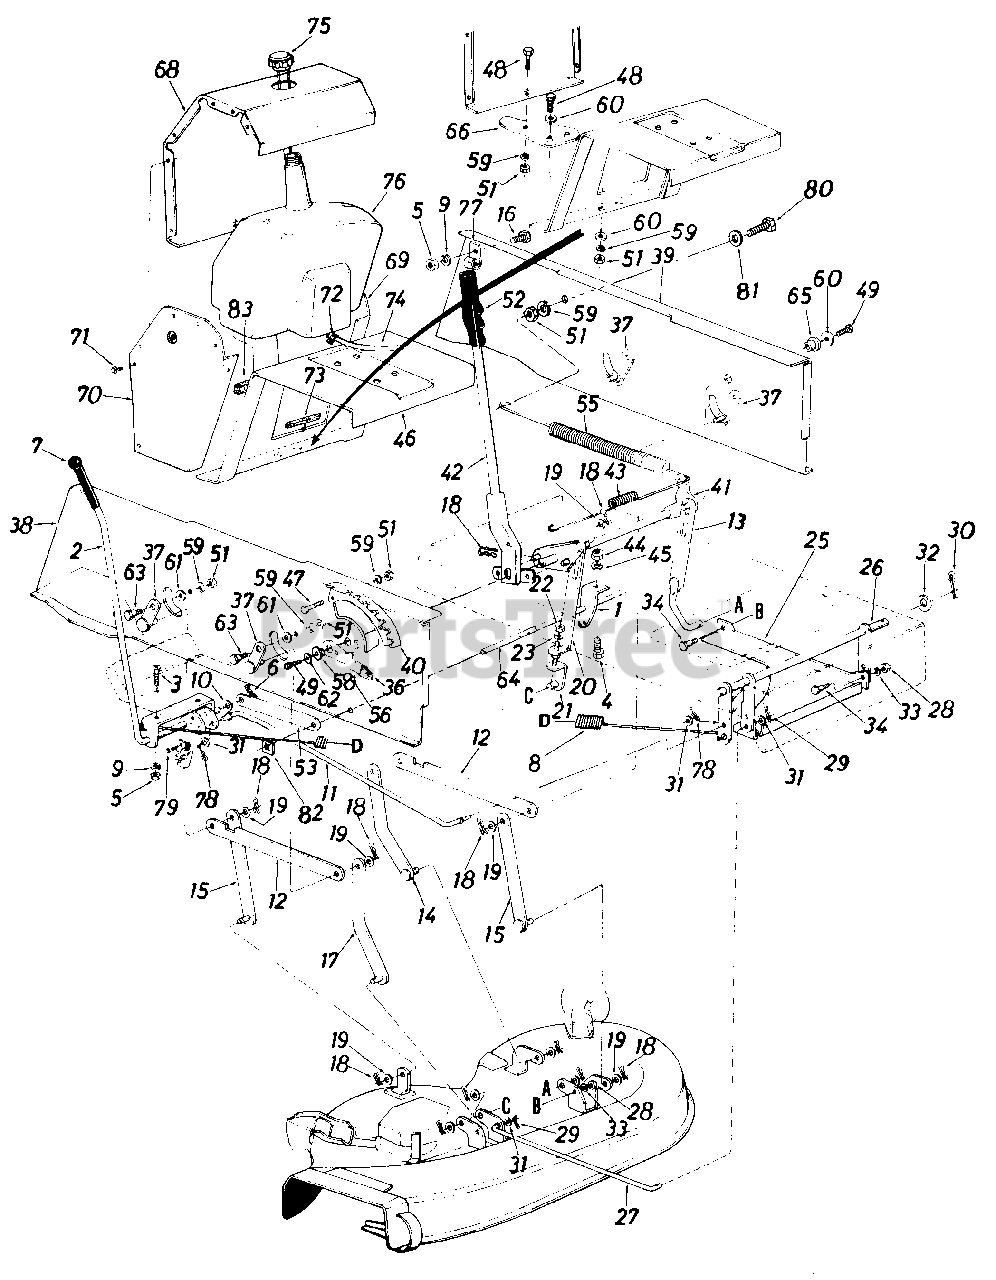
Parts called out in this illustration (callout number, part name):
1	Spring Hanger Bracket
2	Deck Engagement Lever Ass'y.
3	Truss Mach. Scr. 5/16-18 x .75" Lg.
4	Hex Bolt 1/4-20 x .62" Lg.
5	Hex Nut 5/16-18 Thd.
6	Cotter Pin 3/32" Dia. x 1.00" Lg.
8	Ext. Spring .99" O.D. x 22"
9	L-Wash 5/16 I.D.
10	Fl-Wash .510" I.D. x 1.0" 0. D.
11	Drive Deck Control Rod
12	Connecting Rod 3/16 x 1 x 12.5
13	Deck Lift Link Ass'y.
14	Deck Hanger Link Ass'y. Rear L.H.
15	Deck Hanger Link Ass'y.
16	Hex Bolt 5/16-18 x .75" Lg.
17	Deck Hanger Link Ass'y. Front R.H.
18	Inter. Cotter Pin 1/2" Dia.
19	Fl-Wash. .531 I.D. x .93" O.D.
20	Adj. Link Deck Lifting
21	Adj. Lower Link Ass'y.
22	Hex Jam Nut 3/8-24 Thd.
23	L-Wash. 3/8" I.D.
25	Diagonal Brace
26	Stabilizer Shaft Ass'y.
27	Stabiiizer Rod
28	Hex Nut 3/8-16 Thd.
29	Cotter Pin 3/32" Dia. x 1.0" Lg.
30	Cotter Pin 1/8" Dia. x 1.25" Lg.
31	Fl-Wash. .385" I.D. x .620" O.D.
32	Fl-Wash. .635" I.D. x 1.12" O.D.
33	L-Wash. 3/8" I.D.
34	Shoulder Bolt 3/8-16
36	Knob Height Adj.
37	Pivot Link Ass'y.
38	Side Panel Upper Frame R.H.
39	Side Panel Upper Frame L.H.
40	Index Brkt.
41	Lift Shaft Ass'y.
42	Lift Handle Brkt. Ass'y.
43	Ext. Spring .56" I.D. x 32 Coils
44	Hex Nut 1/4-20 Thd.
45	L-Wash. 1/4" I.D.
46	Hitch Plate
47	Hex Bolt 5/16-18 x .75" Lg.
48	Hex Bolt 5/16-18 x 1.00" Lg. (Grade 5)
49	Hex Wash. TT-Tap Scr. 5/16-18 x .62" Lg.
51	Hex Nut 5/16-18 Thd.
52	Grip
53	Link 1.0" x 7.5" x .19
55	Ext. Spring .99" Dia. x 11.00" Lg.
56	Deck Lift Down Stop
58	Flange Brg. .630" I.D.
59	L-Wash. 5/16" I.D.
60	Fl-Wash. .344" I.D. x 1.125" O.D. x .125
61	Fl-Wash. .344" I.D. x .62" O.D. x .063
62	Fl-Wash. .344" I.D. x 1.125" O.D.
63	Shld. Bolt .437" Dia. x .180
64	Running Board Rod
65	Flange Brg. .632" I.D.
66	Hitch Bar
68	Gas Tank Housing Main Panel
69	Side Panel L.H. Gas Tank
70	Side Panel R.H. Gas Tank
71	Truss Mach. B-Tapp Scr. #10 x .50" Lg.
72	Hose Clamp .406" Dia.
73	Trim Strip 5" Lg.
74	Gas Line 44" Lg.
75	Gas Tank Cap
76	Gas Tank
77	Hose Clamp
78	Cotter Pin 3/32" Dia. x .75" Lg.
79	Hex Wash. Hd. Tap Scr. 1/4 x.50" Lg.
80	Hex Bolt 5/16-18 x 1.50" Lg.
81	Fl-Wash. .344" I.D. x .875" O.D.
82	Speed Nut for .500" Dia. Stud
83	Foam Strip 3/8" x 1-1/8" x 1-1/2" Lg.
